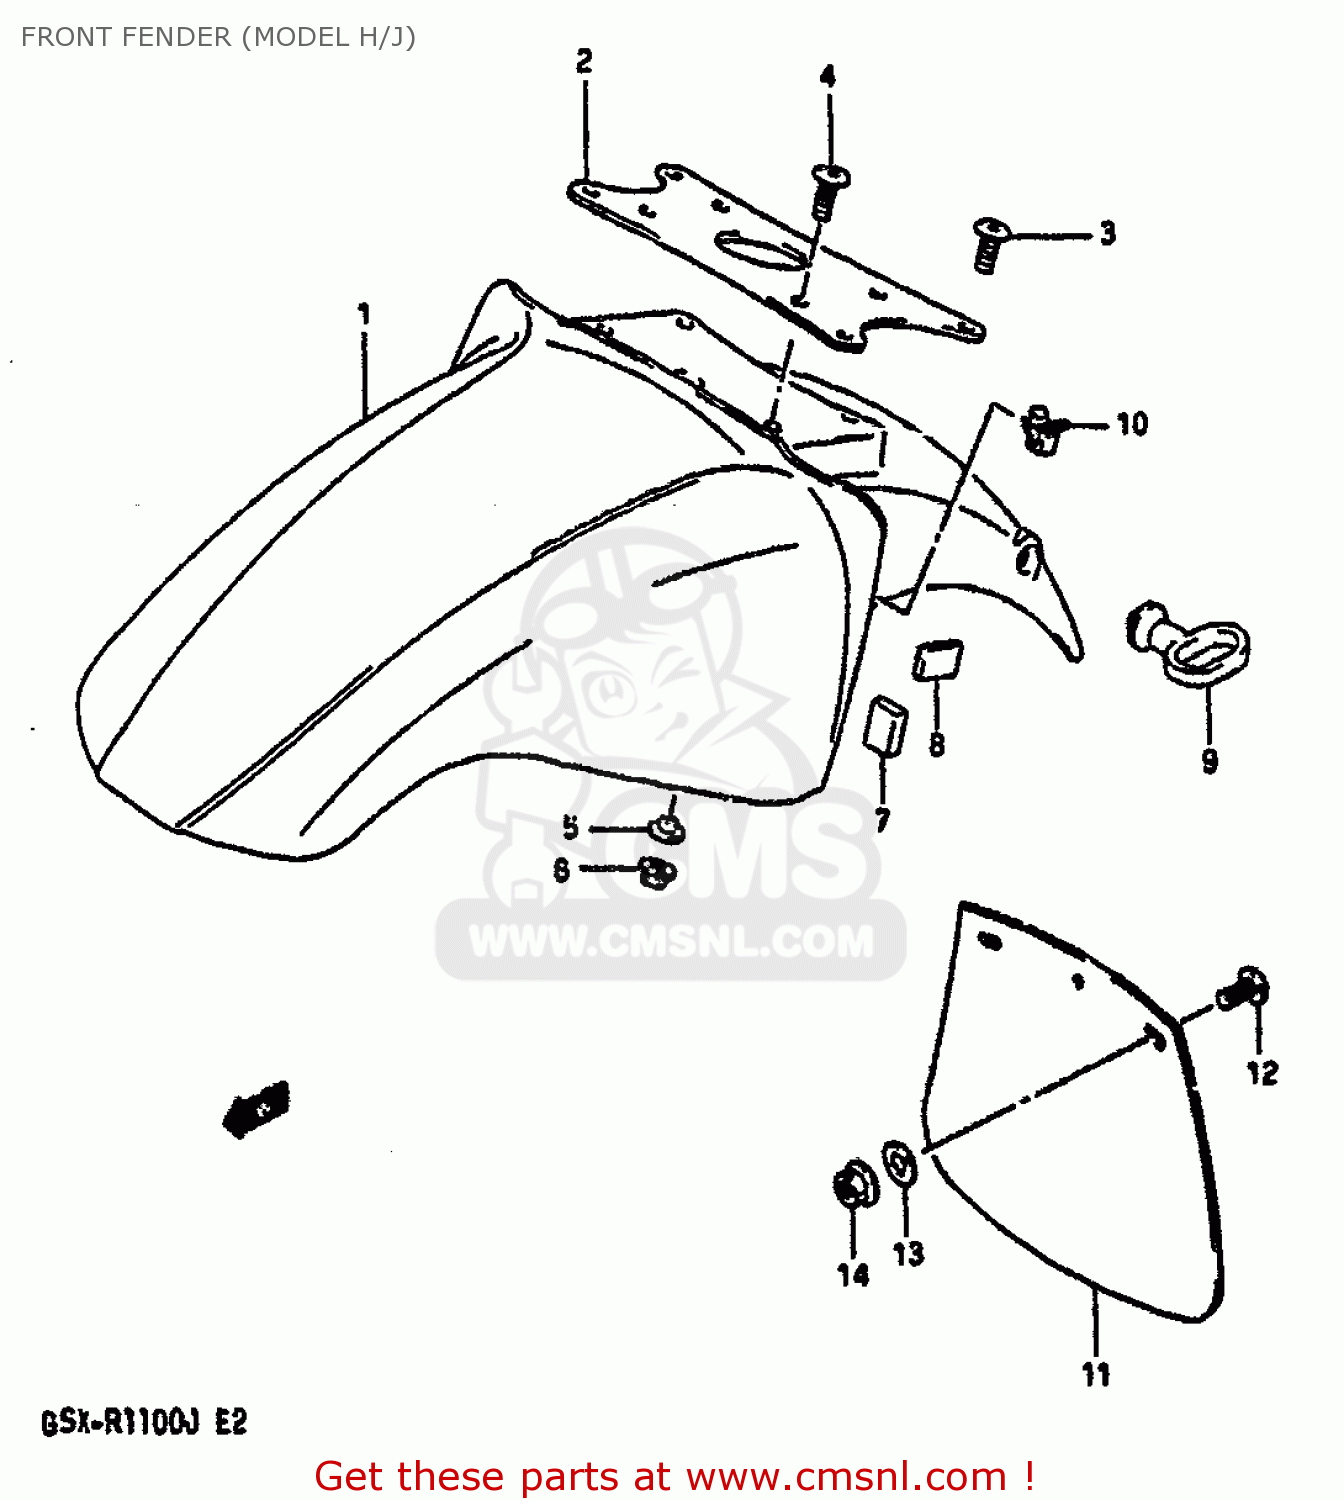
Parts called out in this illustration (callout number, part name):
1	FENDER,FRONT
2	BRACE,FRONT FENDER
3	SCREW(8X16)
4	SCREW(5X14)
5	WASHER
6	NUT
7	CUSHION,FRONT FENDER,S
8	CUSHION,FR FENDER SIDE
9	GUIDE,CABLE
10	CLIP
11	MUD GUARD
12	SCREW
13	WASHER (5.5X16X1.2)
14	NUT
